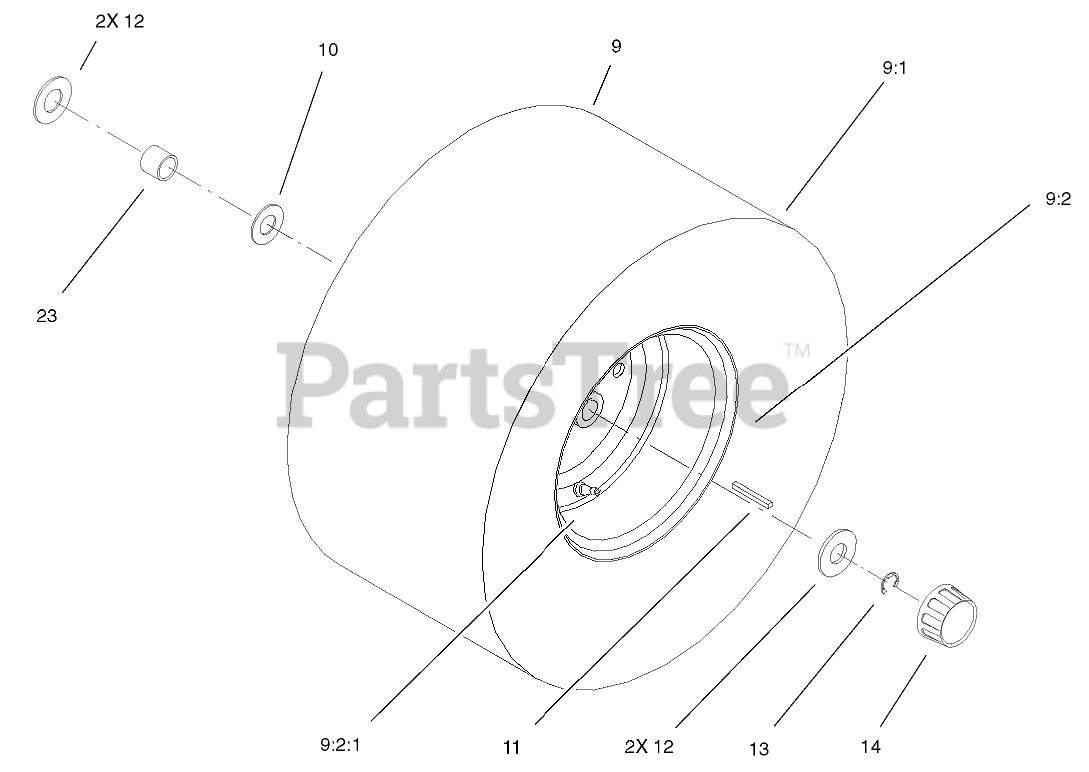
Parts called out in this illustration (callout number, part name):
9	REAR WHEEL & TIRE ASM
9:1	TIRE
9:2:1	STEM-VALVE
10	WASHER-THRUST
11	KEY-SQUARE
12	WASHER-PLAIN
13	E-RING
14	CAP-HUB
23	SPACER-WHEEL
